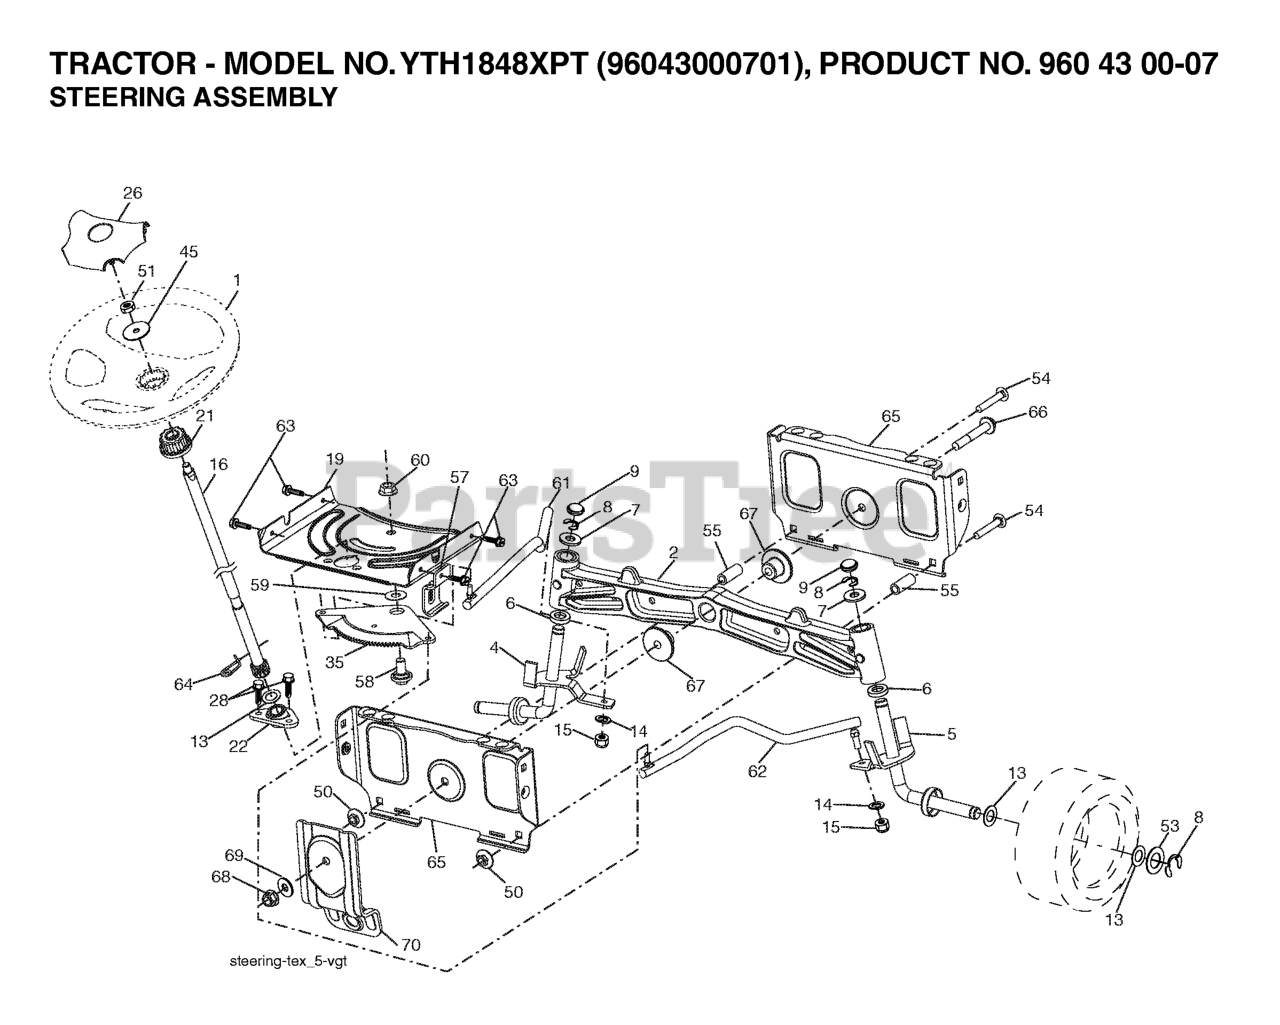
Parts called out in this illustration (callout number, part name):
1	WHEEL.STEERING.LEGEND2.GRY
2	AXLE.CAST.IRON
4	SPINDLE.ASM.LH.DDL.GT
5	SPINDLE.ASM.RH.DDL.GT
6	THRUST WASHER
9	CAP.SPINDLE.BLACK
14	WASHER, LOCK 3/8
15	NUT CROWNLOCK 3/8-24
16	SHAFT.STEER.STEALTH.DD
19	PLATE.STEER.DDL.NLT/NG
21	ADAPTER, WHEEL STNG..
22	BUSHING.ASM.STEERING.A
26	INSERT.CAP.STRG.WH.GRAY
28	SCREW, 3/8-16X3/4
35	GEAR.SECTOR.PLATE.DDL.
45	WASHER 9/16"ID, 2 3/8"OD
51	NUT.HEX.1/2-20
53	WASHER.HARDENED
57	BRKT.UPSTOP.GT/LT.TEX
58	BOLT.SHOULDER.SECTOR.P
59	WASHER.THURST.SECTOR.S
60	NUT FLANGE LOCK 5/8-11
61	DRAGLINK.LH.BALLSTUD.D
62	DRAGLINK.RH.BALLSTUD.D
63	SCREW
64	RETAINER.CLIP.SPRING.S
66	BOLT HEX FGHD 7/16-14 X 3 SERR
67	BUSHING.PM.FRONT AXLE
68	NUT.LOCK.FLANGE.7/16
70	BRKT.DECK.SUSPENSION.F
73	WASHER.1.5X.505X.118
